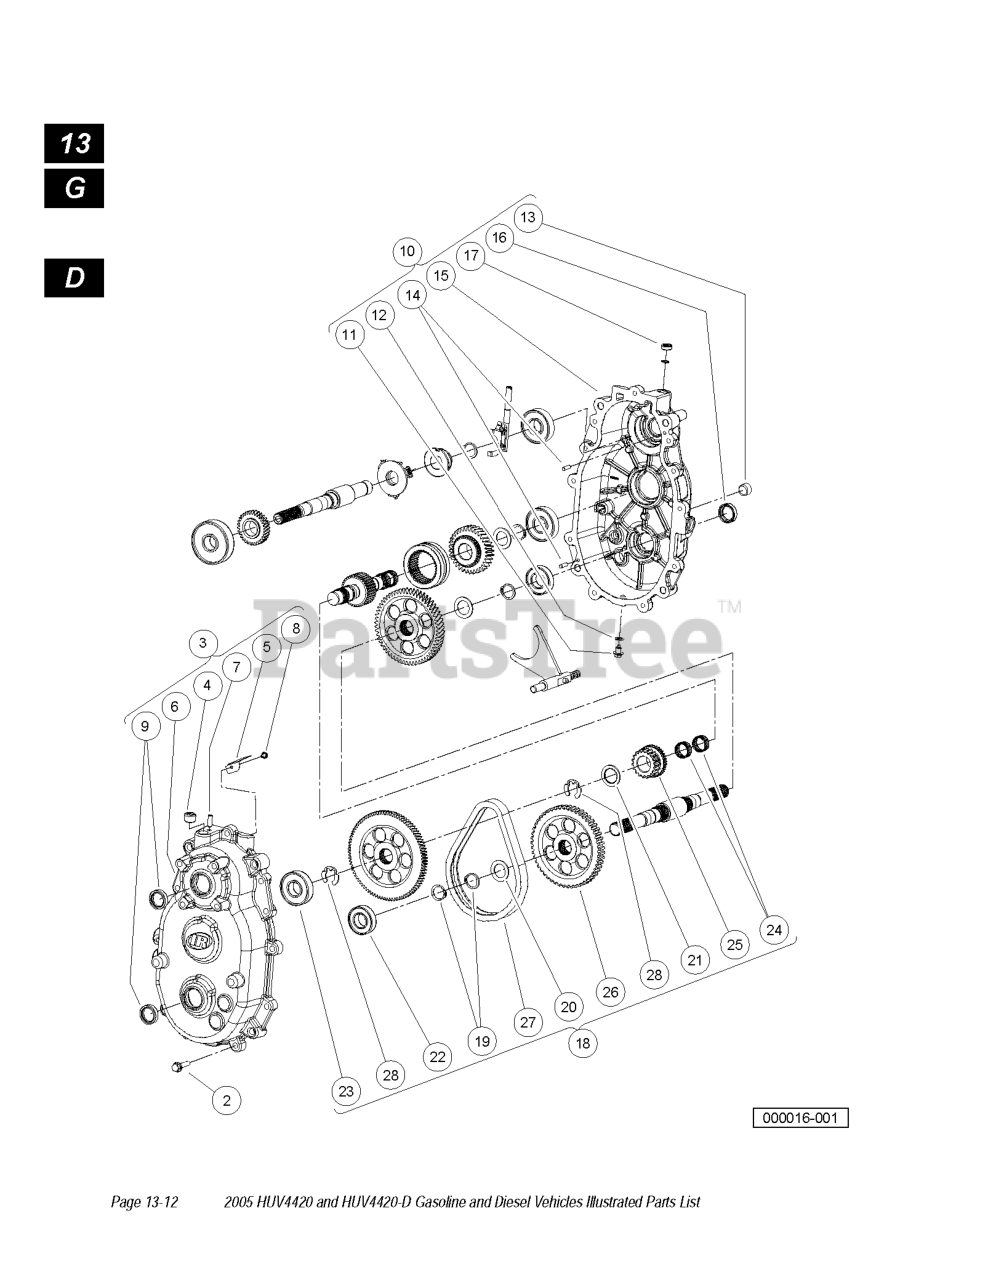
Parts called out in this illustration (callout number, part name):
1	TRANSMISSION, PARALLEL SHAFT
2	SCREW, HEX FLANGE, M8 X 35
3	ASM-GEAR CASE REAR
4	PLUG, SQUARE SKIT, 1/12-14,PTF
5	OIL, DEFLECTOR
7	VENT, TRANS
8	SCREW, TAPPING #10-24 X .375
9	SEAL, TRIPLE, 25 X 35 X 7.8
10	ASM-GEAR CASE FRONT
11	PLUG,3/8-16, HEX FLANGE
12	WASHER, .625 X .382 X .60
13	PLUG, SQUARE SKIT, 1/12-14,PTF
14	PIN, DOWEL, 6 X 20
16	SEAL, TRIPLE, 25 X 35 X 7.8
17	SEAL, DUAL LIP
18	KIT-REVERSE GEAR REPAIR
19	RING, RETAINING, BASIC EXTERNA
20	WASHER, THRUST, 1.007 X .062
21	WASHER, 26.231 X 39.167 X 1.57
22	BEARING, BALL, 6205 C3
23	BEARING, BALL, 6305 C3
24	BEARING, NEEDLE, SPLIT CAGE
28	RING, RETAINING, E-RING, PO-10
